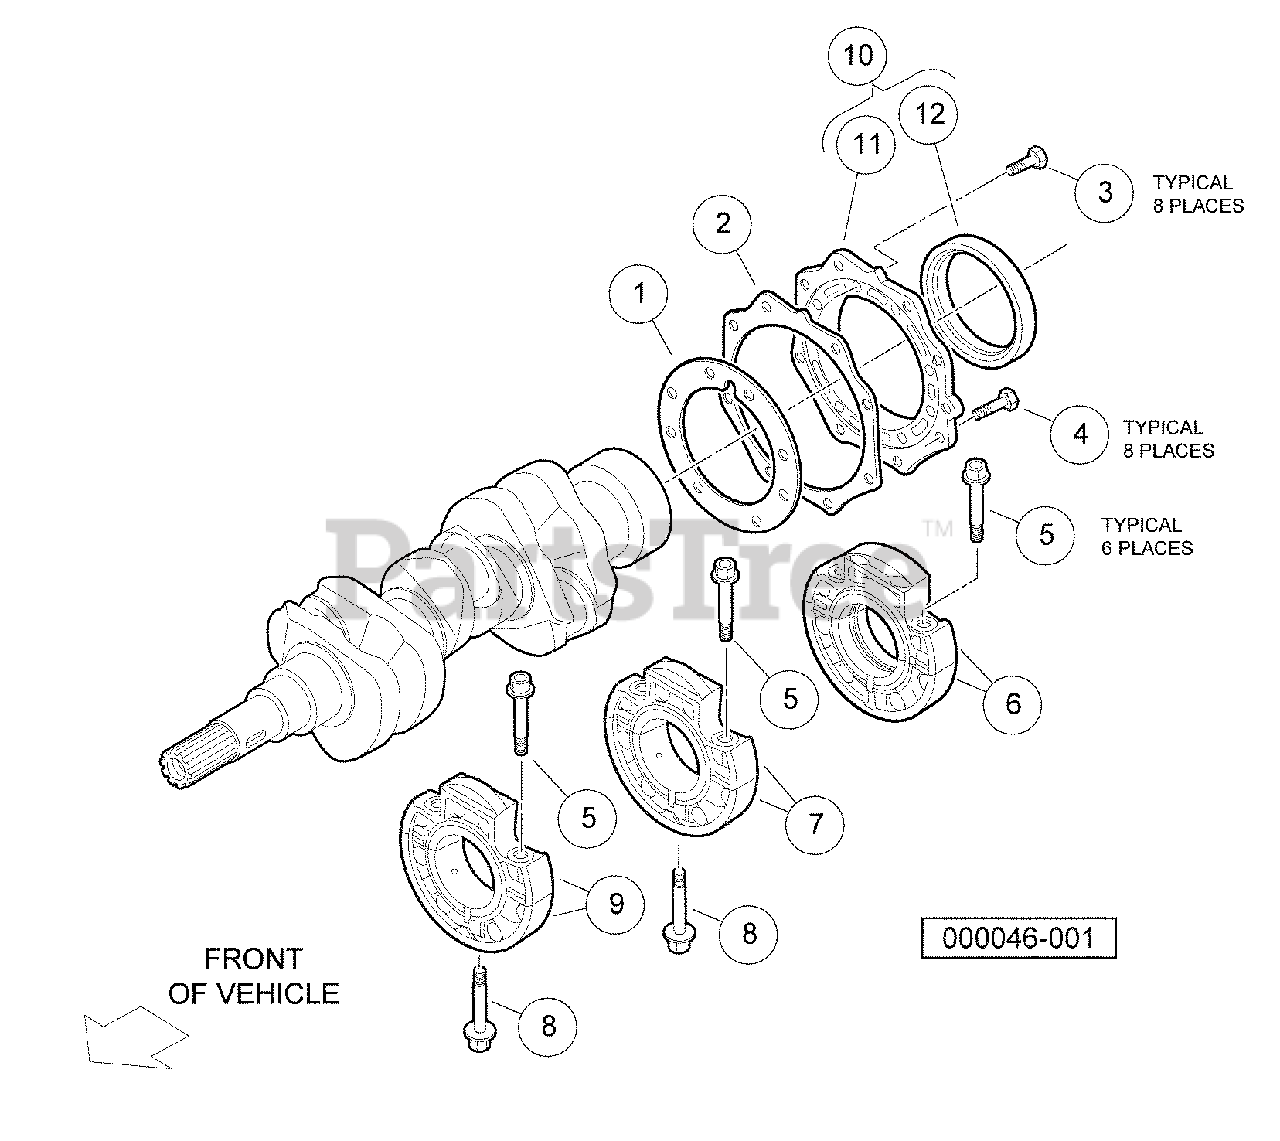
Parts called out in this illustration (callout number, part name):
1	Gasket, Bearing Case
2	Gasket, Cover
3	Bolt, M6 X 1 X 20
4	Bolt, M6 X 1 X 22
5	Bolt, Bearing Case, Top
6	Assy Case, Main Brg, First
7	Assy Case, Main Brg, Sec
8	Bolt, Bearing Case, Bottom
9	Assy Case, Main Brg, Third
10	Assy, Cover, Bearing Case
11	Cover, Bearing Case
